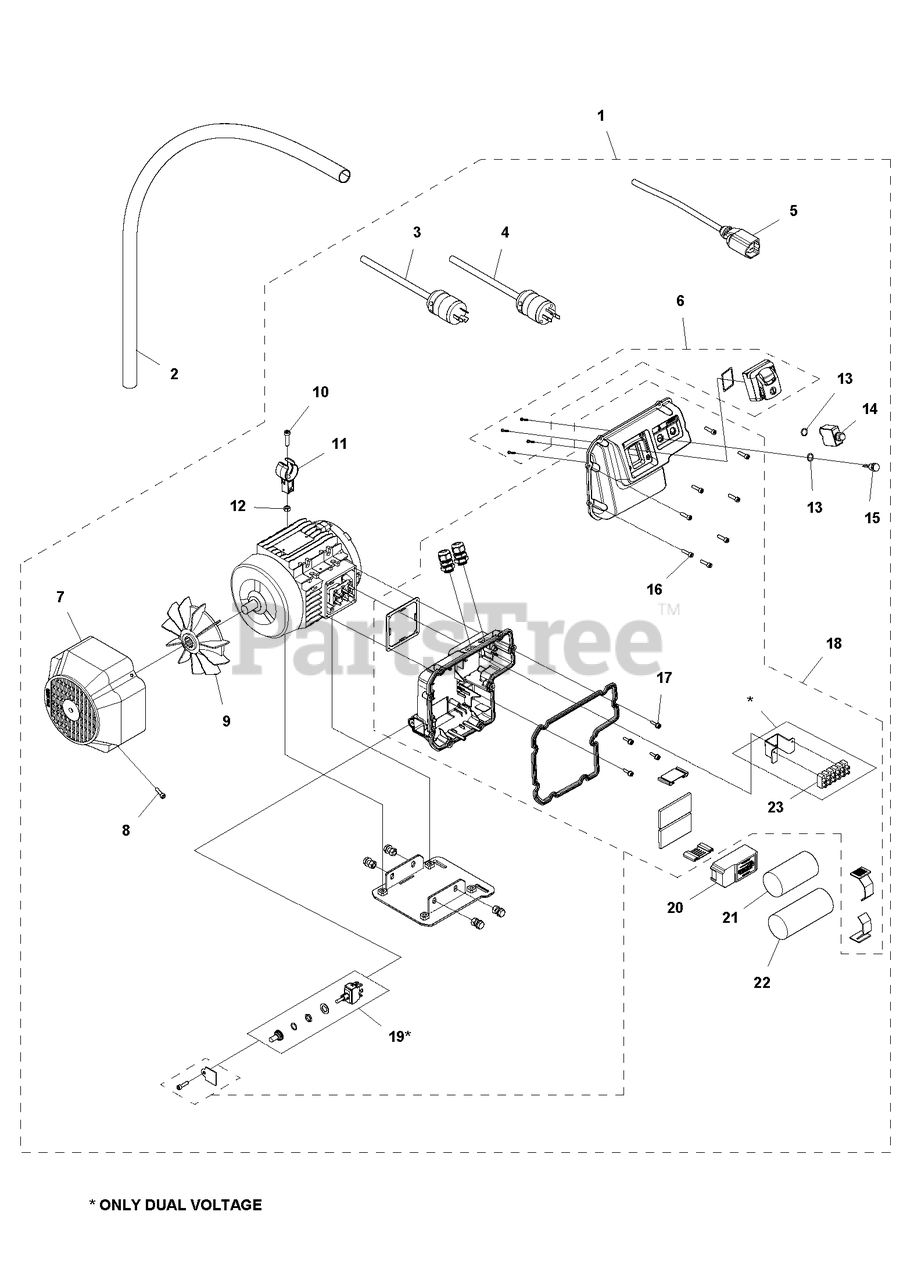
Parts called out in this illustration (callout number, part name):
1	MOTOR115V/230V,1.5kW, 60Hz CPL
1	MOTOR115V,1.1 kW, 60Hz CPL
3	CABLEUsed for: 585 22 54-04
4	CABLEUsed for: 585 22 54-03
7	FAN COVERUsed for: 585 22 54-04
7	FAN COVERUsed for: 585 22 54-03
9	FANUsed for: 585 22 54-04
9	FANUsed for: 585 22 54-03
10	SCREW IHSCM
12	HEXAGON LOCKING NUT
14	CIRCUIT BREAKERUsed for: 585 22 54-04
14	CIRCUIT BREAKERUsed for: 585 22 54-03
16	SCREW IHSCM
19	SWITCH KITDual Voltage Only
21	CAPACITORUsed for: 585 22 54-04
21	CAPACITORUsed for: 585 22 54-03
22	CAPACITORUsed for: 585 22 54-04
22	CAPACITORUsed for: 585 22 54-03
